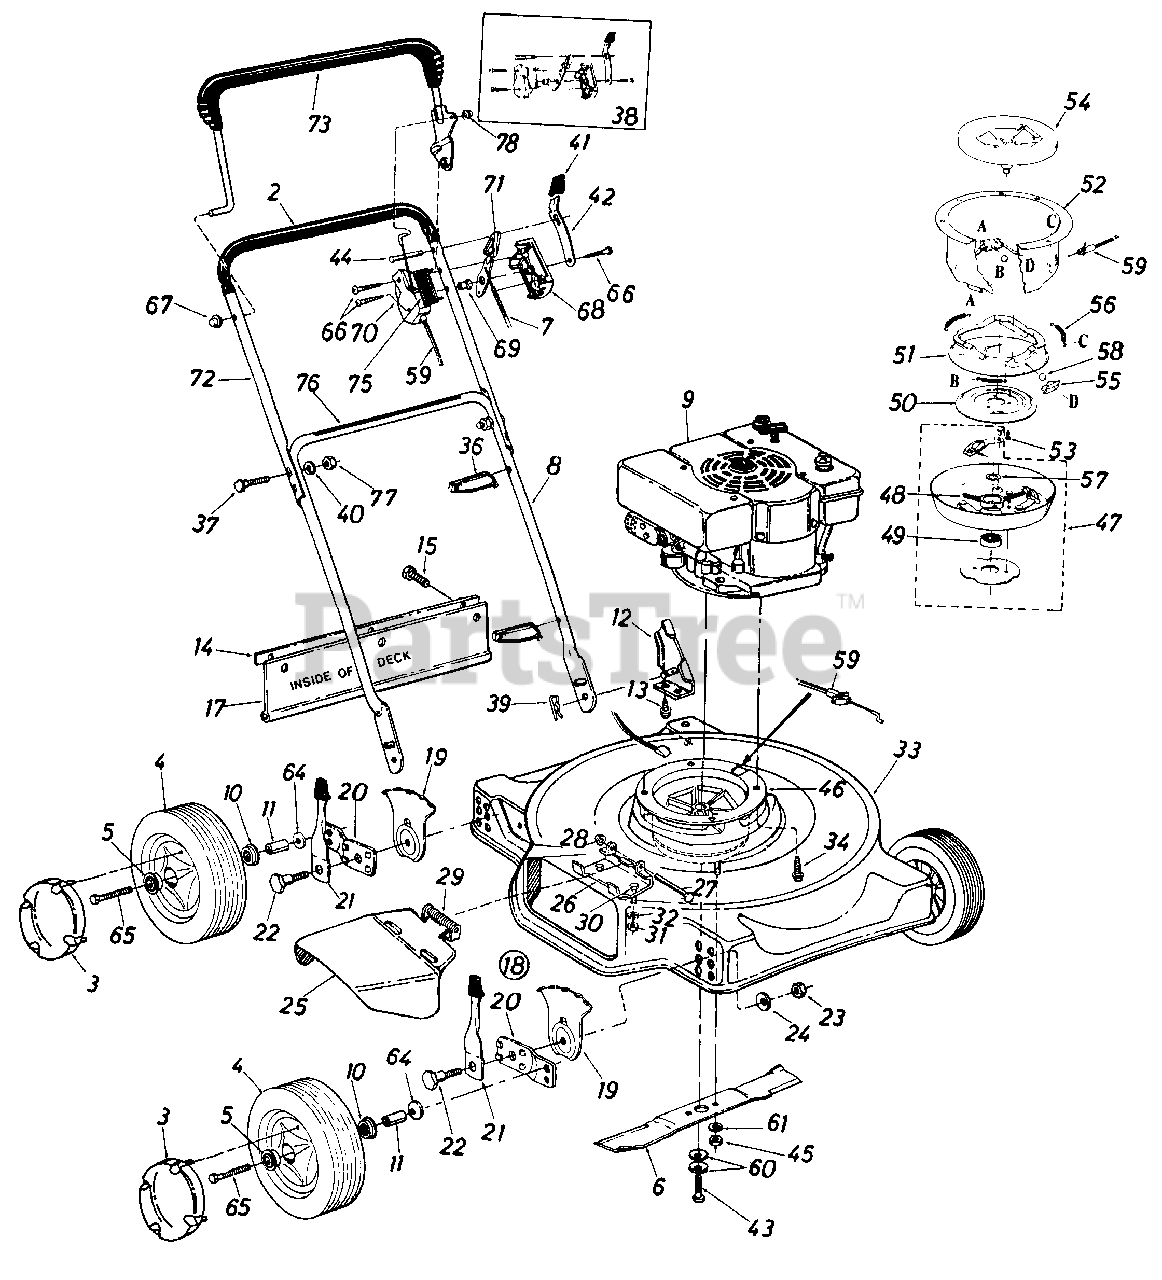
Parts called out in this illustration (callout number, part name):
3	Hub Cap
4	Wheel Ass'y. Comp.
5	Ball Bearing 3/8" I.D.
6	22" Blade
7	Throttle Control Wire 39"
8	Lower Handle
10	Ball Bearing 1/2" I.D.
11	Spacer
12	Handle Mount Brkt. Ass'y. L.H.
13	Hex Wash. Hd. B-Tap Scr. 5/16-18 x .50" Lg.
14	Retaining Strip
15	Hex Wash. Hd. AB-Tap Scr. 1/4 " x .62 " Lg.
17	Rear Flap Ass'y.
18	Height Adj. Ass'y. R.H.
19	Height Adj. Plate
20	Pivot Bar
21	Spring Lever w/Knob
22	Shld. Bolt .500" Dia. x .375
23	Hex Nut 3/8-16 Thd.
24	Bell-Wash. .39" I.D. x 1.4" O. D.
25	Chute Deflector Ass'y. Comp.
26	Deflector Hinge Plate
27	Pivot Pin
28	Cap Speed Nut 1/4" Rod
29	Torsion Spring
30	Hex Bolt 1/4-20 x .50" Lg.
31	Hex Nut 1/4-20 Thd.
32	L-Wash. 1/4" I.D.
33	22" Deck Ass'y.
34	Hex Wash. Hd. TT-Tap Scr. 3/8-16 x 1.00" Lg.
36	Cable Tie
37	Carriage Bolt 5/16-18 x 1.75" Lg.
38	Kit Control Housing Comp.
39	Hairpin Cotter
40	L-Wash. 5/16" I.D.
41	Spring Lever Knob
42	Lock Out Spring
43	Hex Cent. L-Bolt 3/8-24 x 2.00" Lg.
44	Lock Pin .75" Dia. x 1.80
45	Special Hex Nut 5/16-24 Thd.
46	Blade Brake Clutch Ass'y. Comp.
47	Clutch Blade Housing Ass'y.
48	Comp. Spring .35" O.D. x 2.00" Lg.
49	Ball Brg. .669" I.D. x 1.574" O. D.
50	Clutching Cone
51	Brake Cup Cone
52	Clutch Housing
53	Hex Wash. TT-Tap Cl.-Scr. 1/4-20 x .75" Lg.
54	Fan Adapter
55	Ball Block
56	Extension Spring .35" O.D. x 1.75" Lg.
57	Fl-Wash. .690" I.D. x 1.060" O. D.
58	Steel Ball .500" Dia.
59	Clutch Cable 43"
60	Bell-Wash. .400" I.D. x .88" O. D.
61	L-Wash. 3/8" I.D.
64	Bell-Wash. .400" I.D. x .88" O. D.
65	Axle Bolt
66	Truss Mach. Hi-B Tap Scr. #12 x 1.50" Lg.
67	Cap Speed Nut 5/16" Rod
68	Control Panel Half
69	Control Disc Pin
70	Clutch Panel Half
71	Throttle Control Lever
72	Upper Handle
73	Control Handle Ass'y.
75	Control Label Throttle
76	Instruction Label Handle
77	Hex Nut 5/16-18 Thd.
78	Push cap
